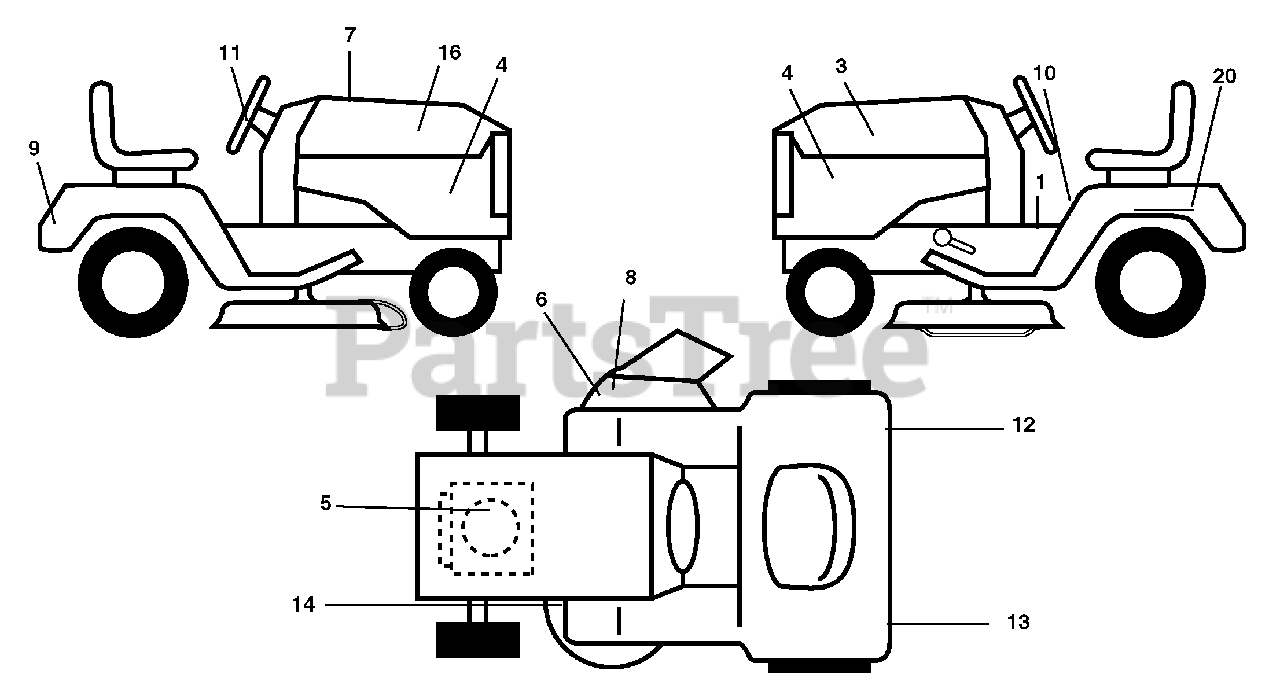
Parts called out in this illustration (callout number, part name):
3	Decal Hood LH
4	Decal Side Panel Logo
5	Decal HP Engine
6	Decal Warning, Keep Hand Away
7	Decal Replacement Parts
8	Decal Deck "B" 42"
9	Decal Fender Logo
10	Decal Fender Danger E/F
11	Decal Ins Strg Whl
12	Decal Fend Refl ector Rh
13	Decal Fend Refl ector Lh
14	Decal V-Belt Schematic
16	Decal Hood Rh
20	Decal Bat Dan/Psn
20	Pad Footrest LH
20	Pad Footrest RH
20	Decal Chass Disconnect
20	Decal Handle Lft Height Adjust
20	Manual Operator's E&F
20	Manual Parts E&F
